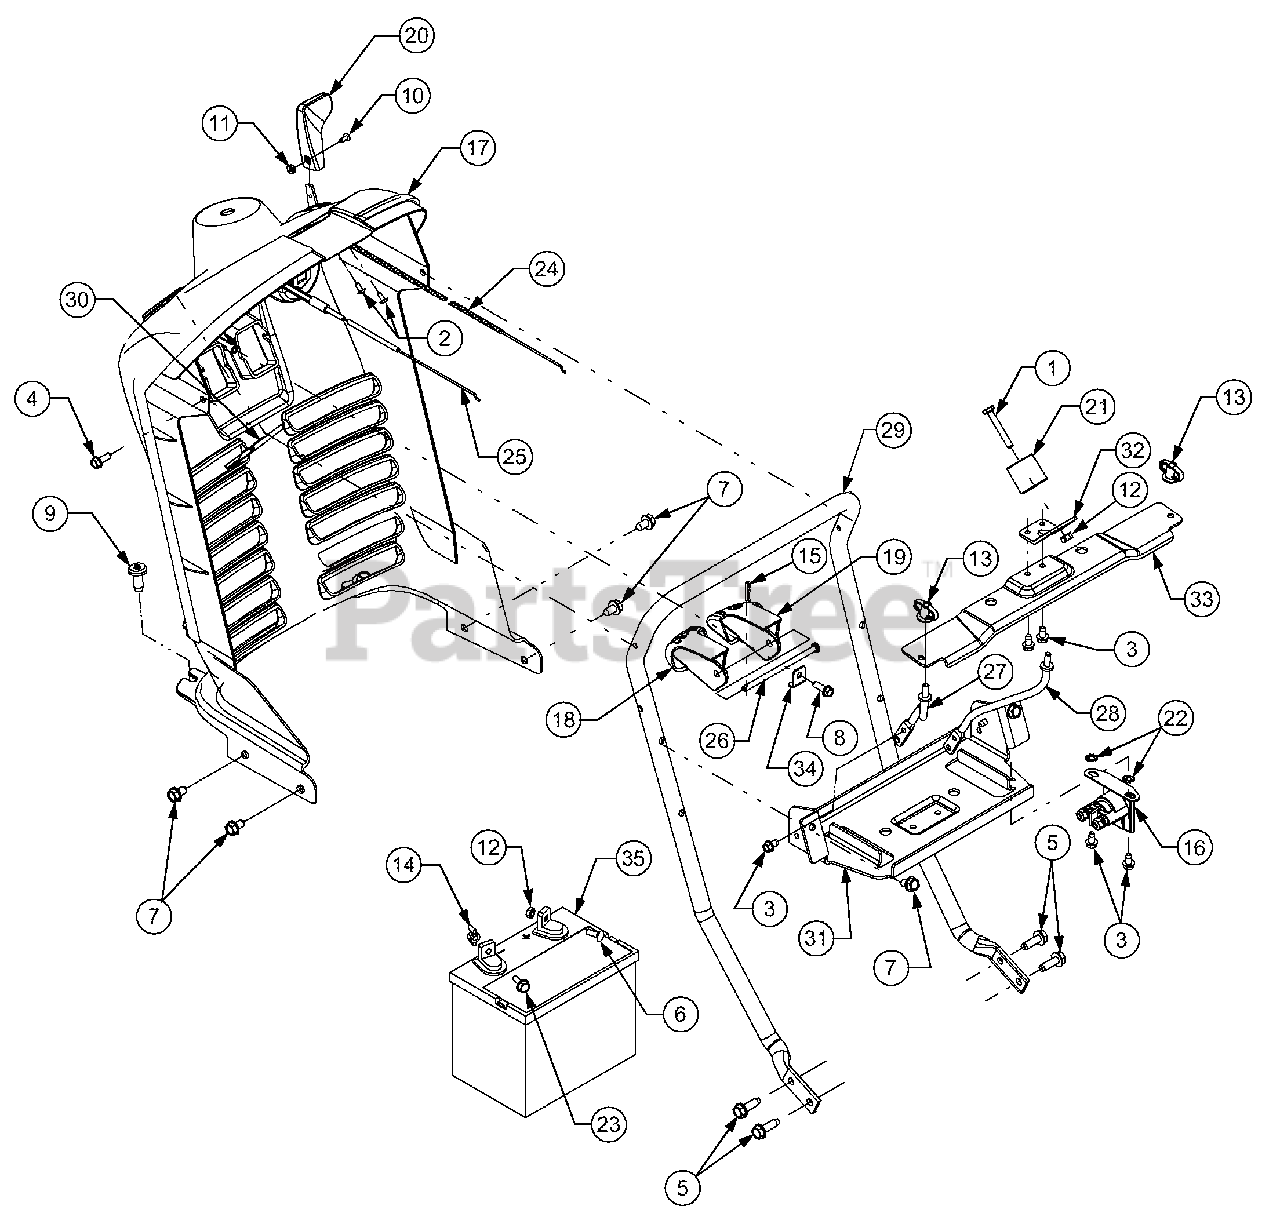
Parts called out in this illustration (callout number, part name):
1	Screw, 1/4-20, 1.75, Gr5
2	Screw, #10-24 X .375
3	Screw, Self-tapping, 1/4-20, 0.500
4	Screw, Hx. Wash. Hd, Tapp. 1/4-20 x .75
5	Screw, Hx. Wash. Hd, Tapp, 5/16-18, .875
6	Screw, Carriage, 1/4-20, .75,
7	Screw, Hx. Wash. Hd, Tapp, 5/16-12 x .75
8	Screw, 1/4-15, 0.750
9	Screw, Torx Hd. Tapp. 5/16-18 x .75
10	Screw, Machine, #8-32, 0.375, Trus Phillips
11	Nut, 8-32
12	Nut, Hex, 1/4-20, Sems
13	Nut, Wing, 1/4-20 w/ Bell Washer
14	Nut, Wing, 1/4-20
15	Internal Cotter Pin, .072 x 1.13
16	Solenoid, 12V, 100 Amp
18	Lever, Dash, Cruise
19	Lever, Dash, Brake
20	Knob, Throttle Control
21	Roller, Latch, Hood
22	Washer, External Lock, 1/4
23	Screw, Shoulder, 1/4-20, .25 x .15
24	Cable, Throttle, 38.0 Lg
25	Cable, Choke, 45.5 Lg.
26	Rod, .250 Dia x 4.25 Lg.
27	Rod, Support, Side Panel RH
28	Rod, Support, Side Panel LH
35	Battery, 275 CCA, Dry
